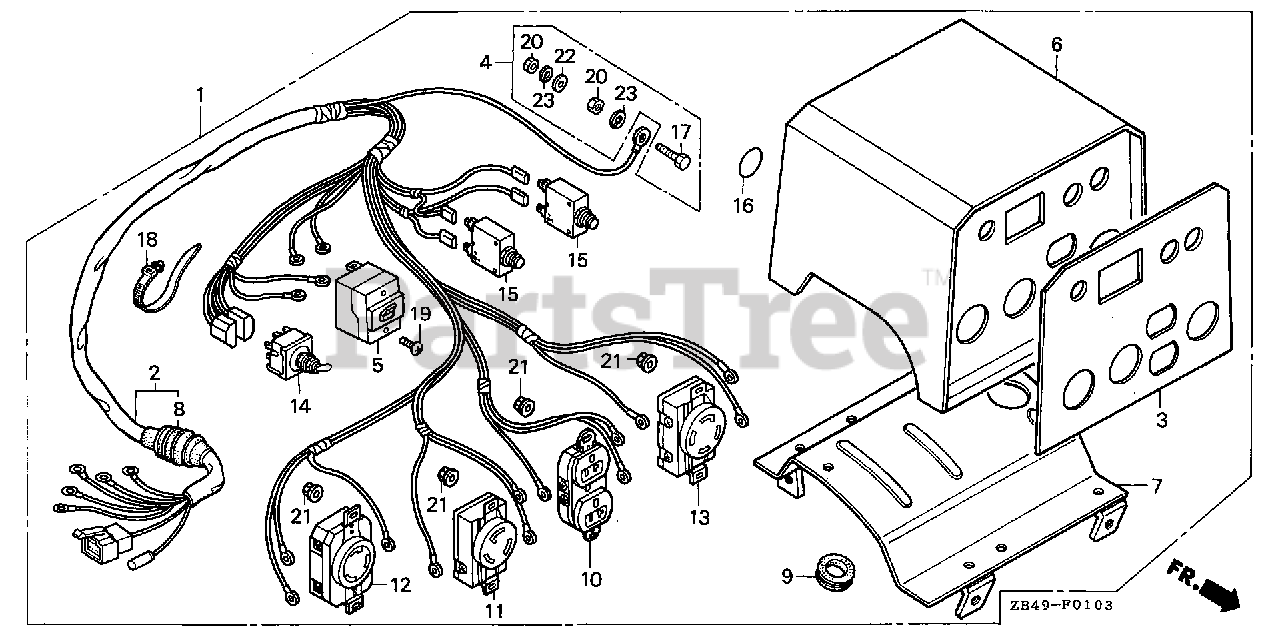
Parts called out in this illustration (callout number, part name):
1	BOX ASSY., CONTROL *R8* (BRIGHT RED)
2	WIRE HARNESS ASSY.
3	MARK, SWITCH PANEL
4	TERMINAL SET, GROUND
5	BREAKER, CIRCUIT (14A)
6	BOX, CONTROL *R280* (POWER RED)
7	PLATE (LOWER) *R280* (POWER RED)
8	GROMMET, A.C. WIRE
9	GROMMET, MAIN WIRE
10	RECEPTACLE (20A/125V)
11	RECEPTACLE (20A/125V) (NOT AVAILABLE)
12	RECEPTACLE (30A/125V)
13	RECEPTACLE (20A-125/250V) (MATSUSHITA) (NOT AVAILABLE)
14	SWITCH ASSY., VOLT CHANGE
15	PROTECTOR, CIRCUIT (20A)
16	MARK, GROUND
17	BOLT, HEX. (6X28)
18	TIE, CABLE (NATURAL 225X5.0)
19	SCREW, PAN (4X6)
20	NUT, HEX. (6MM)
21	NUT, FLANGE (4MM)
22	WASHER, PLAIN (6MM)
23	WASHER, SPRING (6MM)
